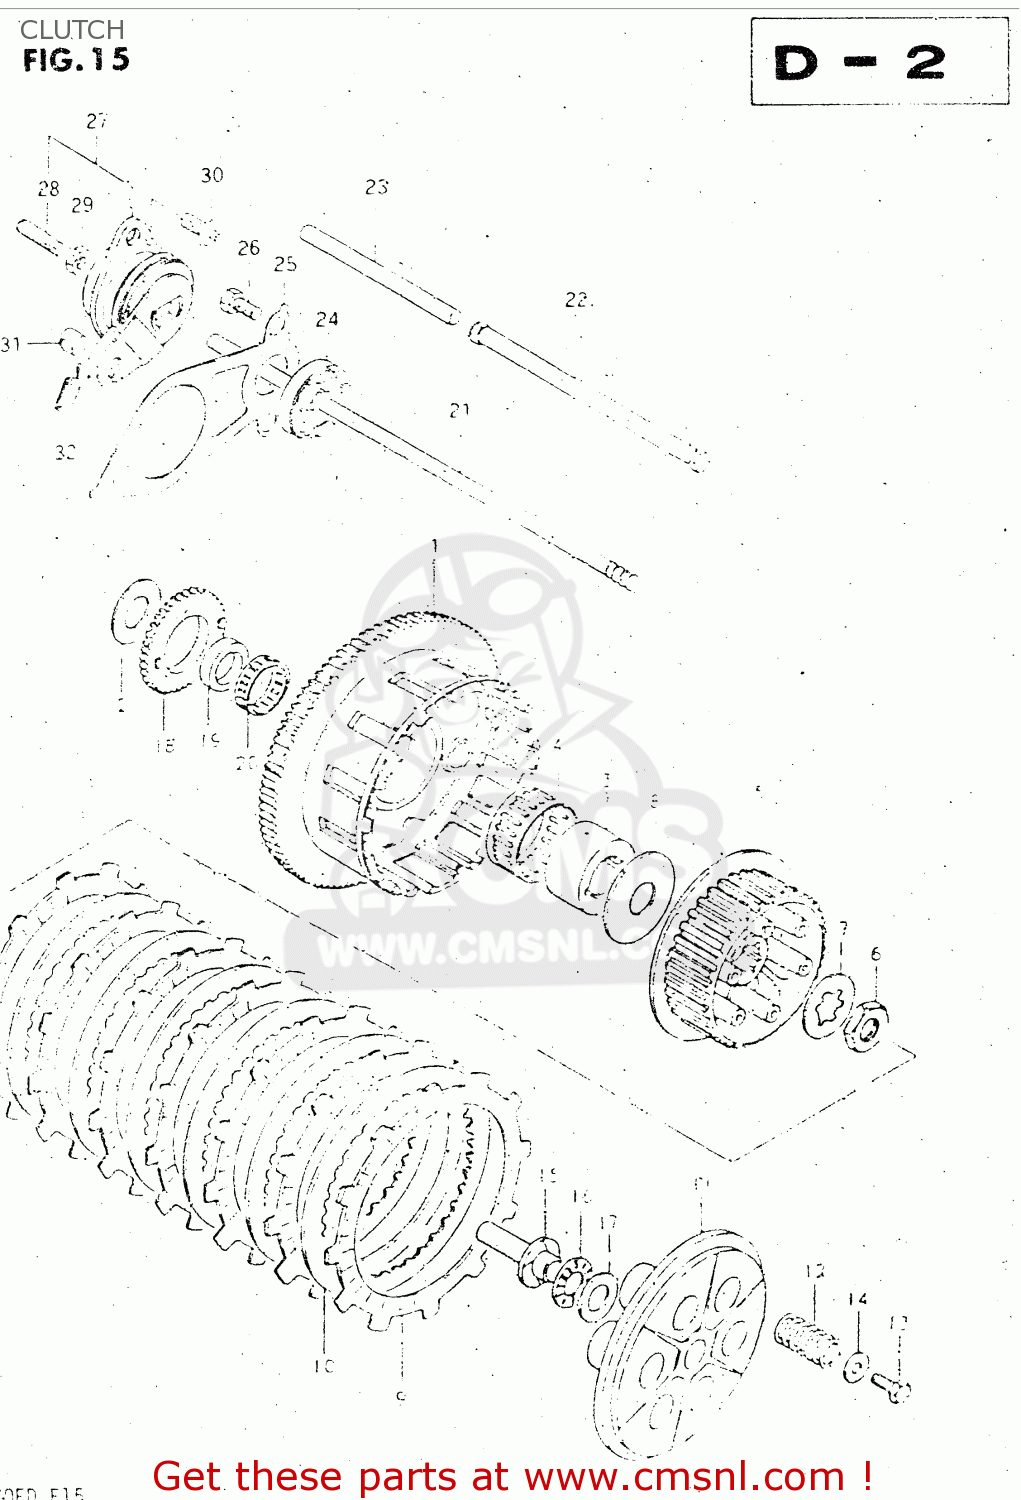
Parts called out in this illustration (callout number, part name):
1	GEAR ASSEMBLY,PRIMARY DRIVE NT:87
2	WASHER
3	SPACER
4	BEARING
5	HUB,CLUTCH SLEEVE
6	NUT
7	WASHER,LOCK
8	WASHER(25X66X3.5)
9	PLATE,CLUTCH DRIVE (NAS)
10	PLATE,CLUTCH DRIVEN (NAS)
11	DISC,CLUTCH PRESSURE
12	SPRING
13	BOLT, UPPER
14	WASHER
15	PIECE,CLUTCH PUSH
16	BEARING(15X28X2)
17	WASHER
18	GEAR,ENG OIL PUMP DRIVE(NT:38)
19	SPACER,OIL PUMP DRIVE GEAR
20	BEARING(36X40X10)
21	ROD,CLUTCH PUSH
22	ROD, RH PUSH
23	ROD,CLUTCH PUSH
24	OIL SEAL
25	PLATE,CLUTCH PUSH ROD
26	BOLT
27	SCREW ASSEMBLY,CLUTCH RELEASE
28	SCREW
29	NUT 6MM
30	SCREW 6X12
31	PIECE,RELEASE ARM END
32	SPRING
